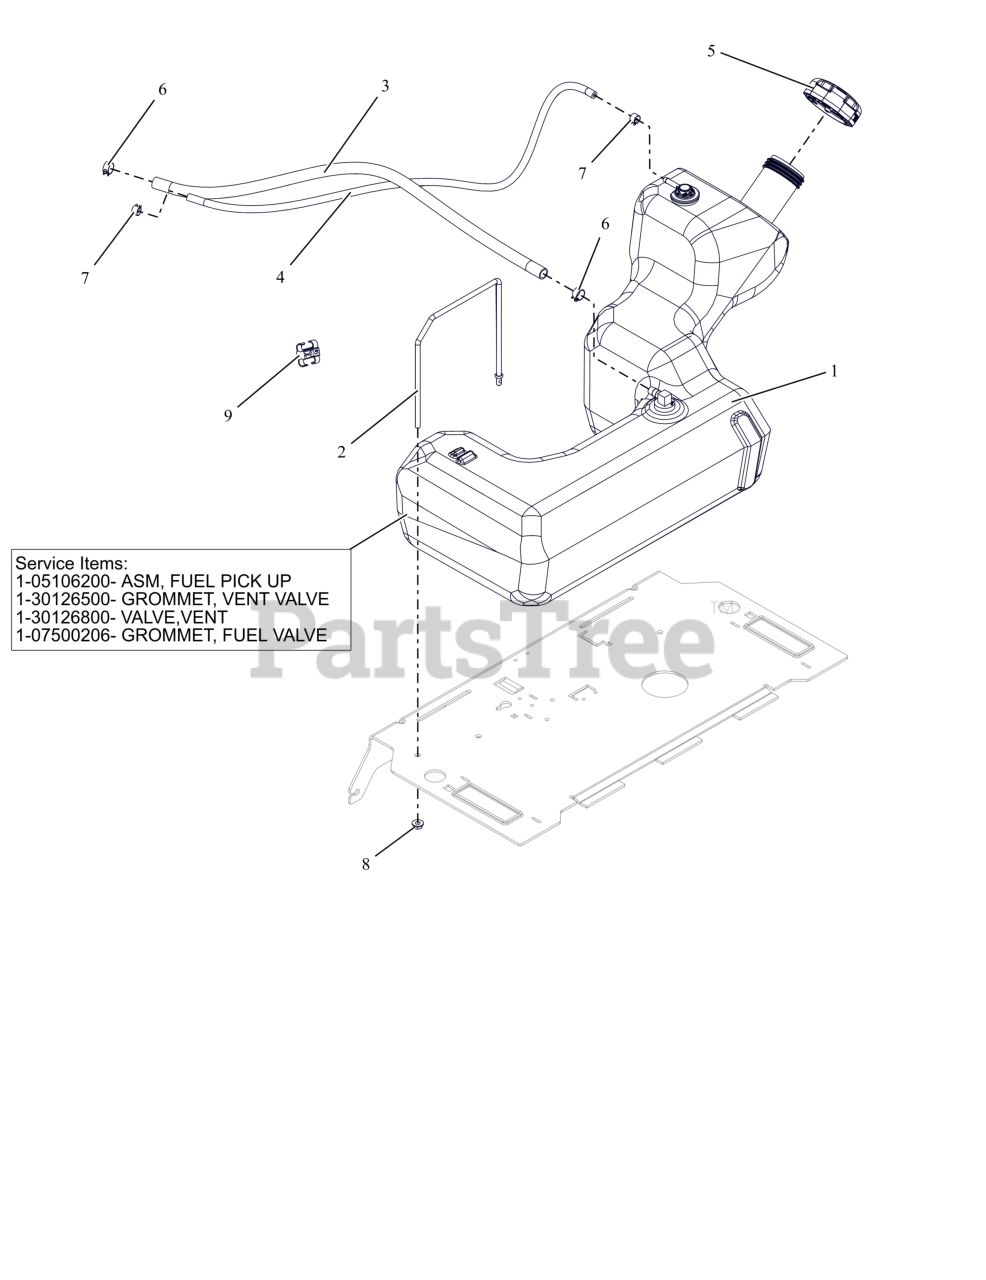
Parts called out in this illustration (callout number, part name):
1	ASM, FUEL TANK - IKON 23
1	ASM, IKON FUEL PICK-UP
1	GROMMET, VENT VALVE
1	VALVE, VENT
1	BSHG-FLG .375X1.062X.625 NITR
2	STRAP, TANK HOLD DOWN
3	1 INCH OF HOSE, .25 LOW-PERM BULK GAS
4	HOSE, .188 30R7 BULK
5	CAP-FUEL- 2.25 RATCHET INLET V
6	CLAMP, FUEL LINE
7	CLAMP-HOSE, SPRING .188
8	NUT-LK-CTR-FLG .25-20 ZC120
9	CLIP, T, .38-.50
